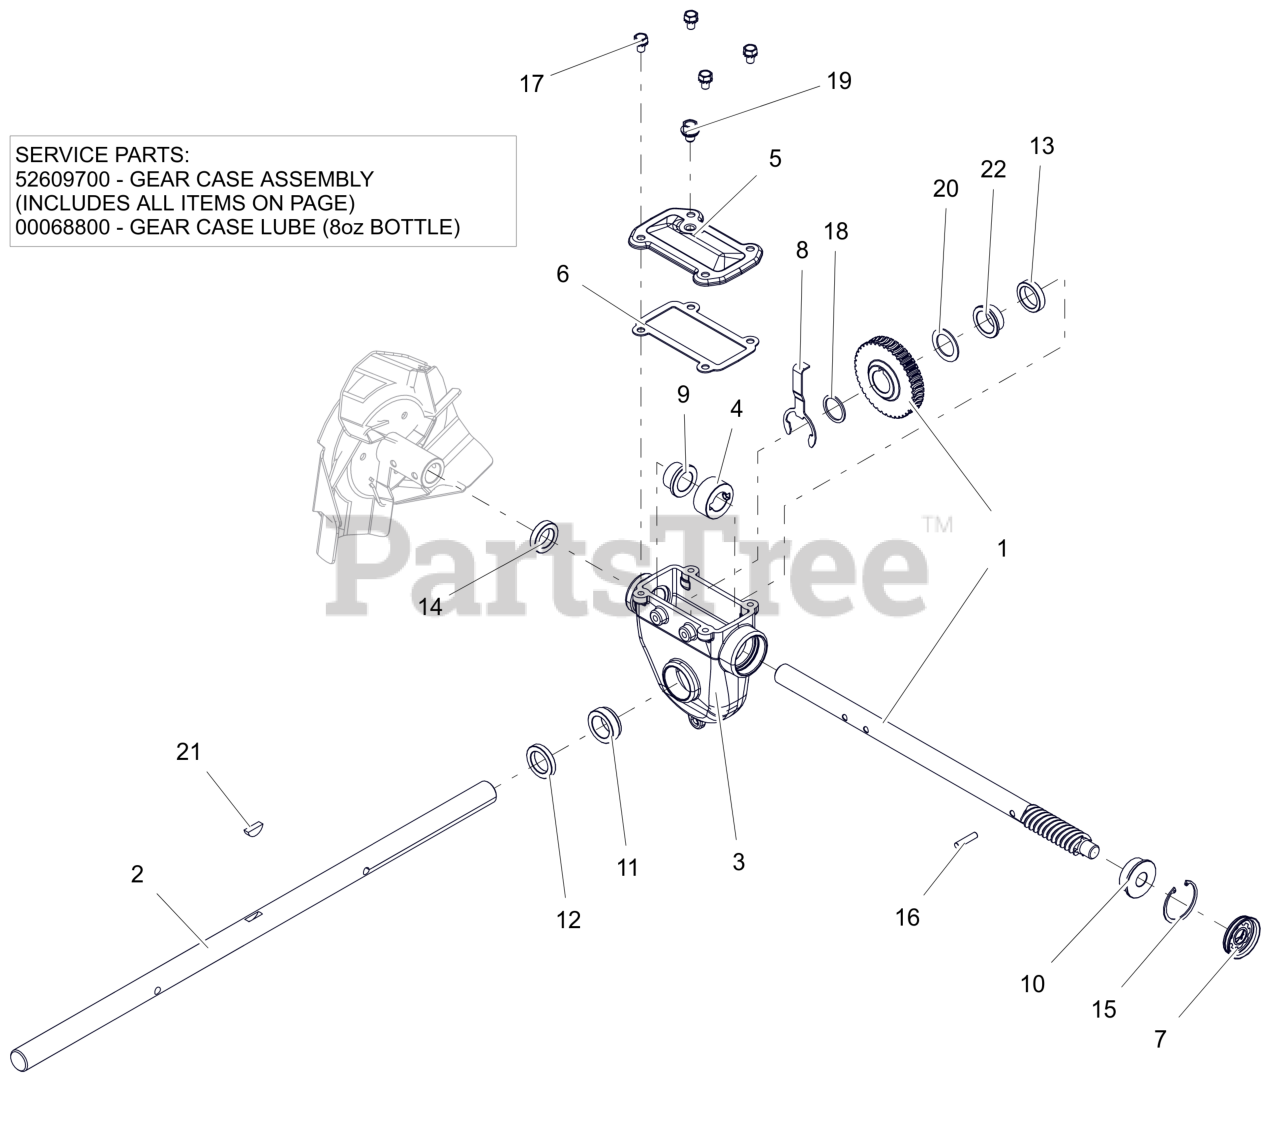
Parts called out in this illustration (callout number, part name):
1	ASSY, WORM SHAFT & GEAR
2	SHAFT, RAKE-28"
3	GEARCASE, LARGE MACHINED
3	GEAR CASE, 28" IRON PRO TOP-LD
3	ARIENS L3 LUBE, 8 OZ BOTTLE
4	THRUST COLLAR, .875"ID SLIPFIT
5	COVER, TOP - LARGE IRON
6	GASKET, TOP - LARGE GEARCASE
7	COVER, GEAR CASE 1.75"
8	BUSHING RETAINER, LARGE
9	BSHG-FLG .879X1.128X.75X1.45
10	BSHG-FLG .628X1.503X.58X1.725
11	BSHG-FLG LARGE, RIGHT
12	SEAL-OIL .999X1.500X.250 TBC29
13	SEAL-OIL .999X1.375X.312 TBC29
14	SEAL-OIL .873X1.375X.312 TBC29
15	RG-RTNG-INT 1.750X.062
16	PIN-STR .250X1.12 6150
17	BLT, SEMS .31-18X.50 G5 ZCC
18	WSHR, FLT 1.010X1.250X.068 ZCC
19	SCR, .380-15X.500 W/SEAL WASHER
20	WSHR, FLT 1.010X1.505X.062 ZCC
21	KEY-WDRF .25X.875 HRD #A
22	BSHG-FLG 1.006X1.128X.555X1.45
